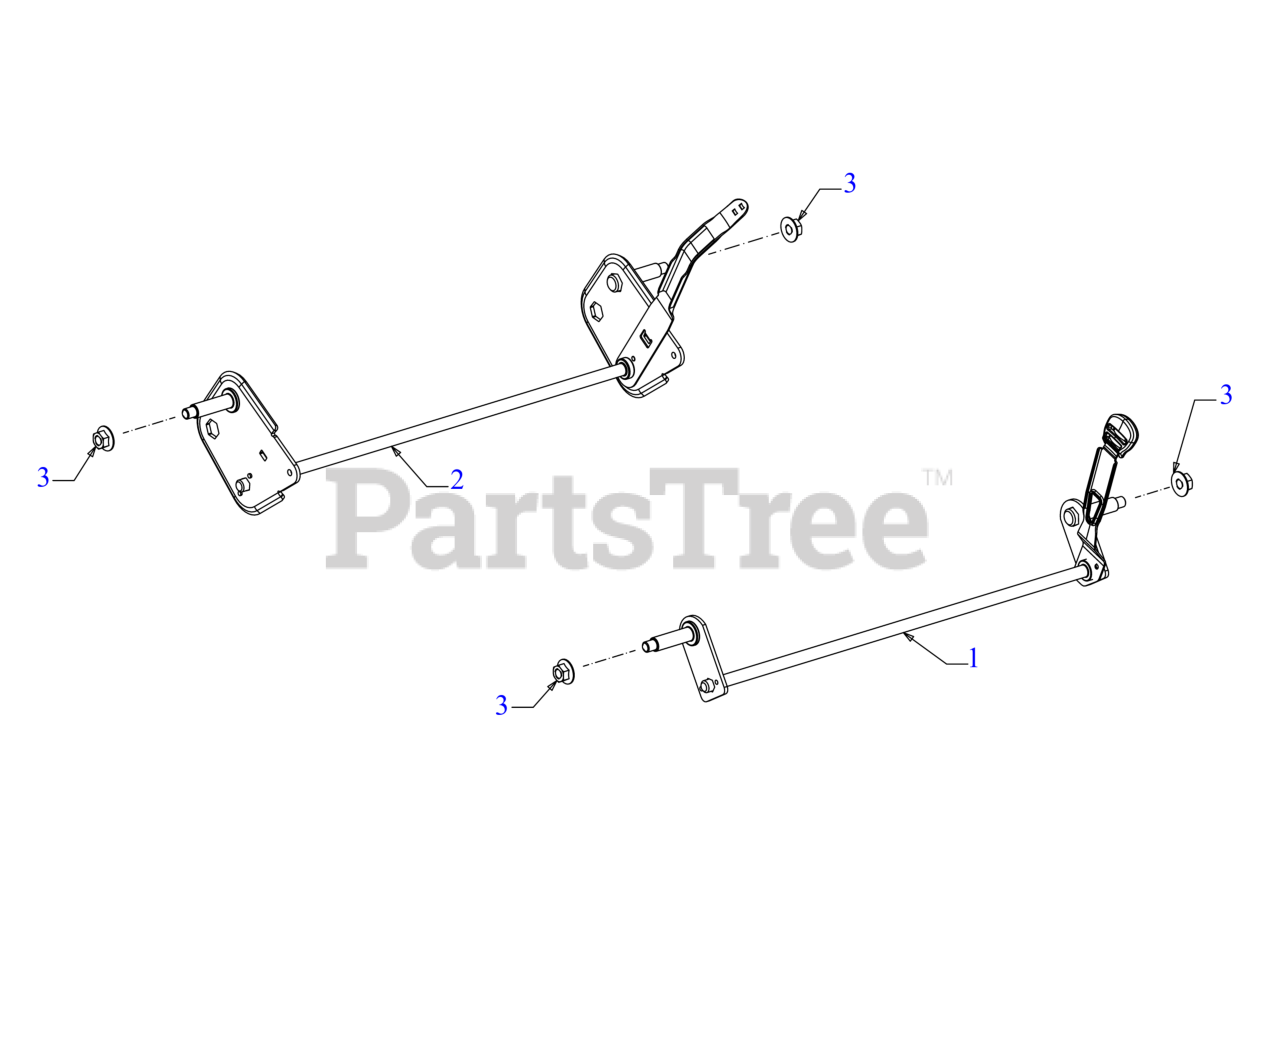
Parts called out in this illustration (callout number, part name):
1	FRONT AXLE ASSEMBLY
2	REAR AXLE ASSEMBLY
3	FLANGE LOCK NUT
